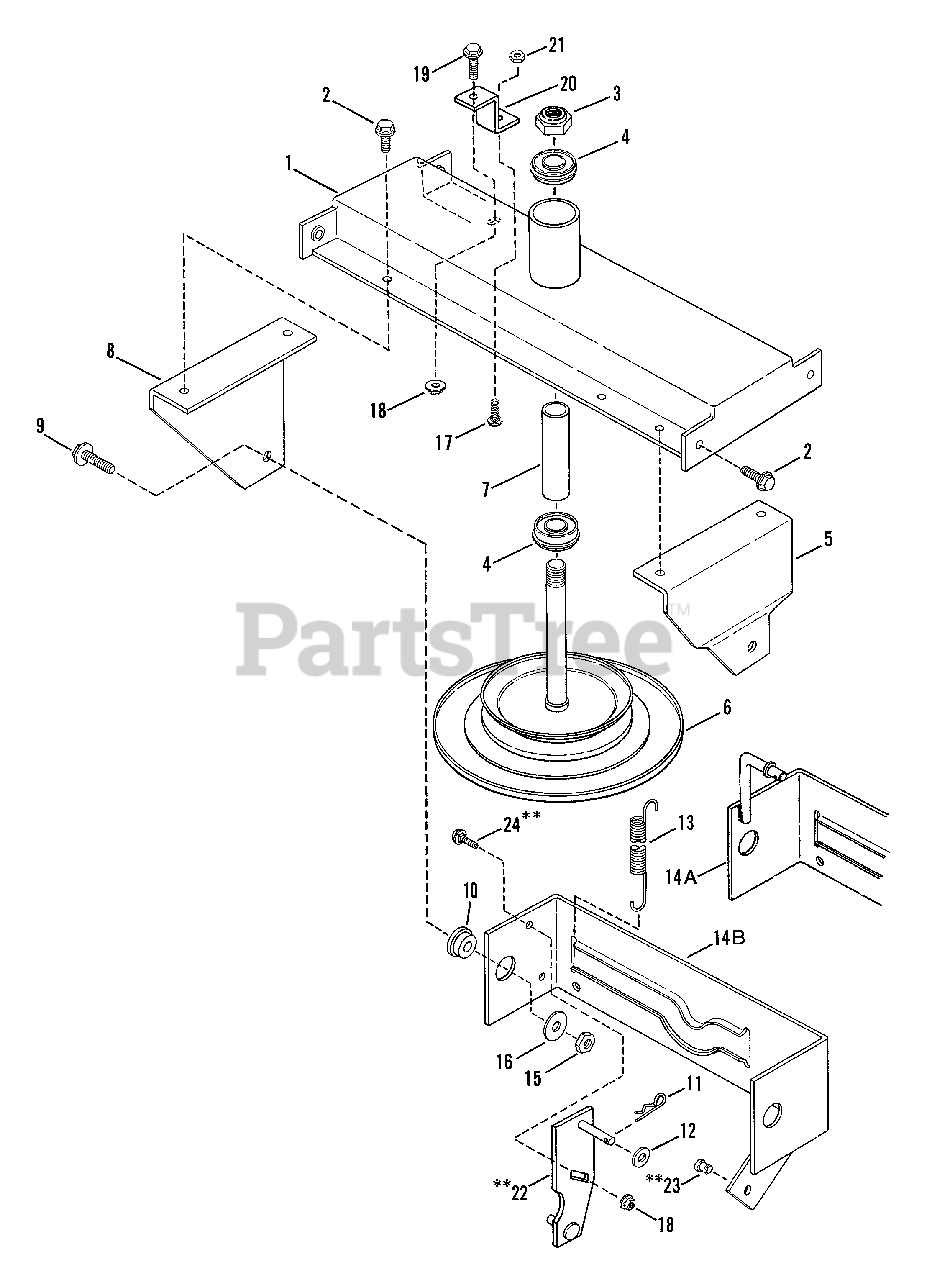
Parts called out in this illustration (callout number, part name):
1	SUPPORT ASSM'Y., Disc Drive
2	SCREW, 5/16-18x1/2" Self-Tap
3	LOCKNUT, 518-18 Hex
4	BEARING
5	BRACKET, Yoke Pivot, L.H.
6	DISC-DRIVE ASSM'Y.
8	BRACKET, Yoke Pivot, R.H.
9	SCREW, 5/16-24x1" Hex Hd. Cap
10	BEARING, Yoke
11	PIN, Hair
12	WASHER, 5/16 Flat
13	SPRING
14A	YOKE, Clutch
14B	YOKE, Clutch
15	LOCKNUT, 5/16-24 Hex
16	WASHER, 5/16 Flat
17	BOLT, 5/16-18x1-1/2" Carriage
18	NUT, 5/16-18 Hex Flange Lock
19	BOLT, 5/16-18x3/4" Hex Flange Lock
20	YOKE STOP ASSEMBLY
21	JAM-NUT, 5/16-18 Hex
22	ANCHOR, Spring
23	BEARING, Nyliner
24	BOLT, 5/16-18x3/4" Carriage
